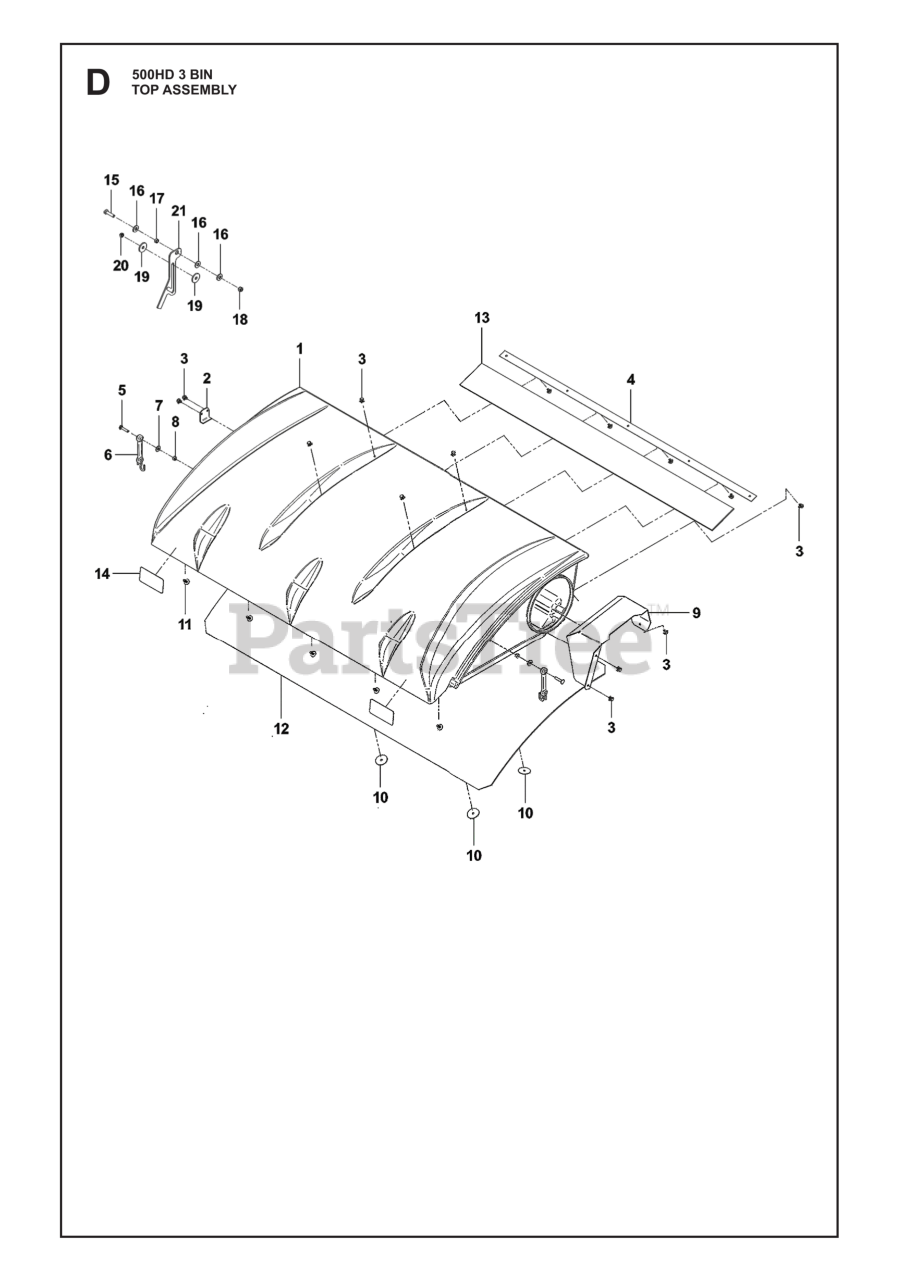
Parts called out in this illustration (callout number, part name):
6	STRAP SHORT RUBBER STRAP W/ S-
8	Hardware
9	DEFLECTORS
16	WASHER 11/32 X 11/16 X 14 GA T
18	NUT HEXAGON FLANGE 5/16-18 ST
20	NUT.CENTERLOCK.5/16-
